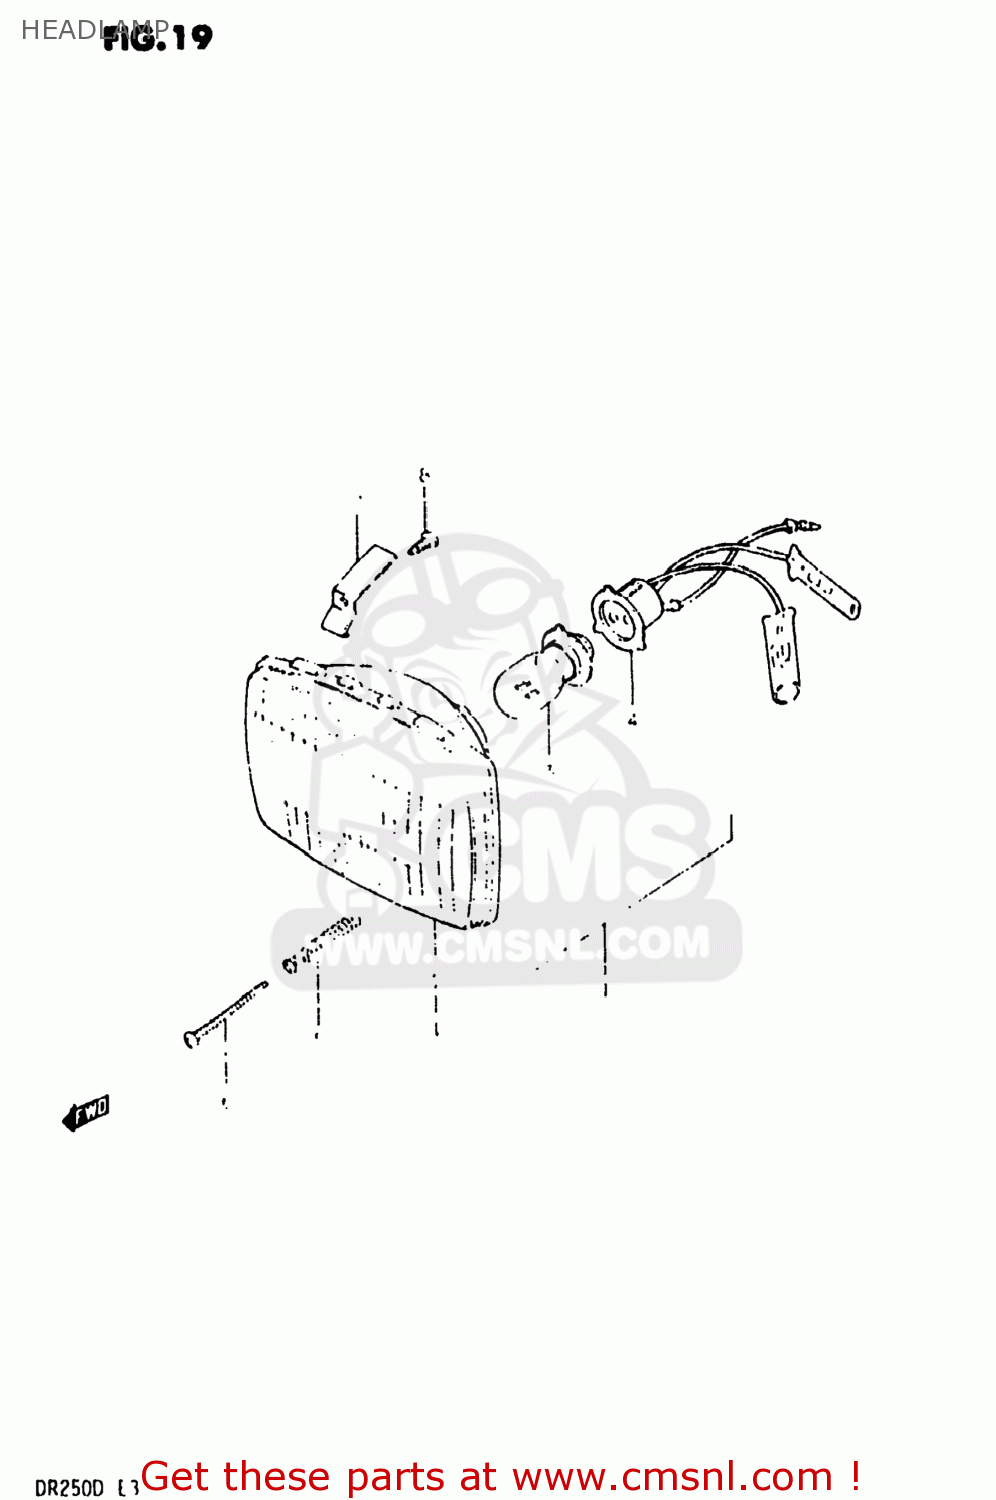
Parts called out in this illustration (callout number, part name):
1	HEADLAMP ASSEMBLY
2	LAMP UNIT
3	BULB(6V15/15W/STANLEY,A3598HA)
4	SOCKET,HEADLAMP
5	SPRING,HEAD LAMP ADJUSTER
6	SCREW,HEADLAMP ADJUST
7	SPRING
8	SPRING,HEADLAMP ADJUST
